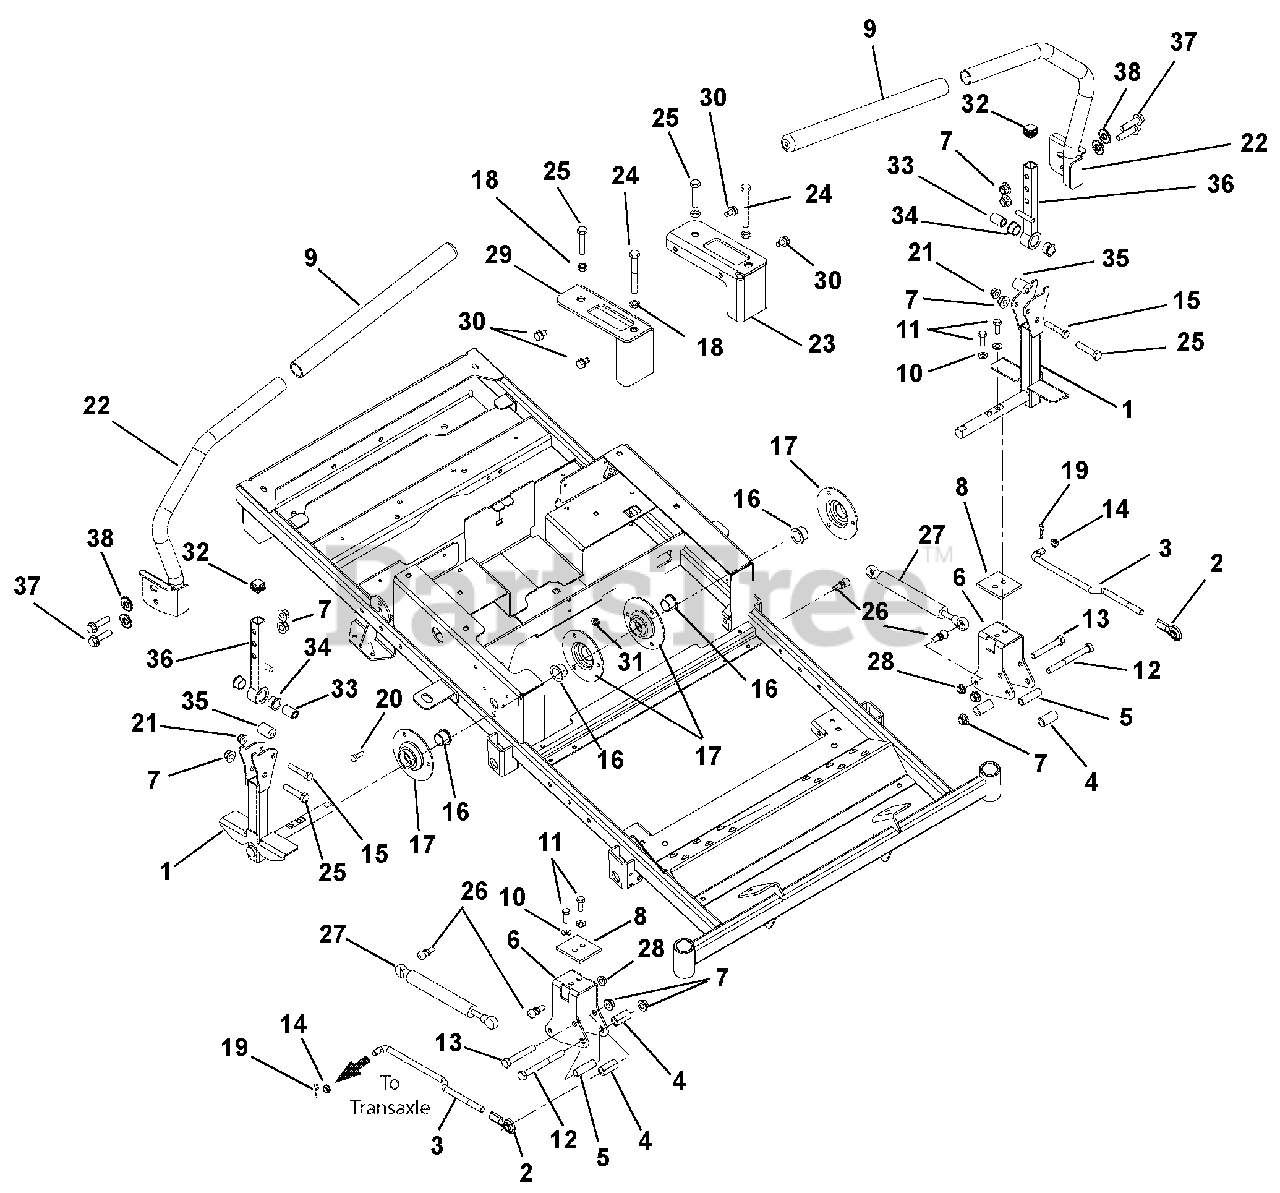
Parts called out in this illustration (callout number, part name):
1	WMT, CONTROL ARM
2	ROD END, .38 RH
3	LINK, TRANSMISSION
4	BSHG, SPCR .390X.625X1.25 PM
5	SPACER, STEERING
6	BRKT, STEERING
7	@NUT-LK-NYL-FLG .38-16 YWZC
8	PLATE, STEERING REINFORCING
9	GRIP, HANDLEBAR 15" FOAM
10	@WSHR-LK .31X.078 REG YWZC
11	BLT-HEX .31-18X1.00 GR8 YWZC
12	@BLT-HEX .38-16X3.75 GR5 YWZC
13	@BLT-HEX .38-16X2.50 GR5 YWZC
14	BUSHING, POLYLINER-.38 SNAPIN
15	@BLT-HEX .31-18X1.75 GR5 YWZC
16	BSHG-FLG .750X1.000X.625X1.250
17	BEARING FLANGE
18	NUT-HEX-JAM .375-16 YWZC
19	PIN-HAIR INT .08X.18X1.18 YWZC
20	@BLT-HEX .25-20X.75 GR5 YWZC
21	@NUT-LK-NYL-FLG .31-18 YWZC
22	WMT, STEERING HANDLE RH
22	WMT, STEERING HANDLE LH
23	BRACKET, LH SPEED CONTROL
24	BLT-HEX .38-16X3.00 GR5 FTH YZ
25	BLT-HEX .375-16X1.750 FTD YWZC
26	STUD- BALL
27	DAMPER, CONTROL
28	@NUT-LK-TOP-FLG .31-18 YWZC
29	BRACKET, RH SPEED CONTROL
30	@SCR-TAP .31-18X.50 HWH TR YWZ
31	@NUT-LK-TOP-FLG .25-20 YWZC
32	CAP PLUG, SQ 3/4-14-20 RIBBED
33	SPACER, .375X.625X.970 (PM)
34	BSHG-FLG, .625X.75X.450X.875
35	BSHG, ECCENTRIC .328X.750X.970
36	WMT, UPPER CONTROL ARM
37	BLT-SERHFWH .375-16X1.25 YWZC
38	@WSHR-FL-STL.406X.812X.065 YWZ
